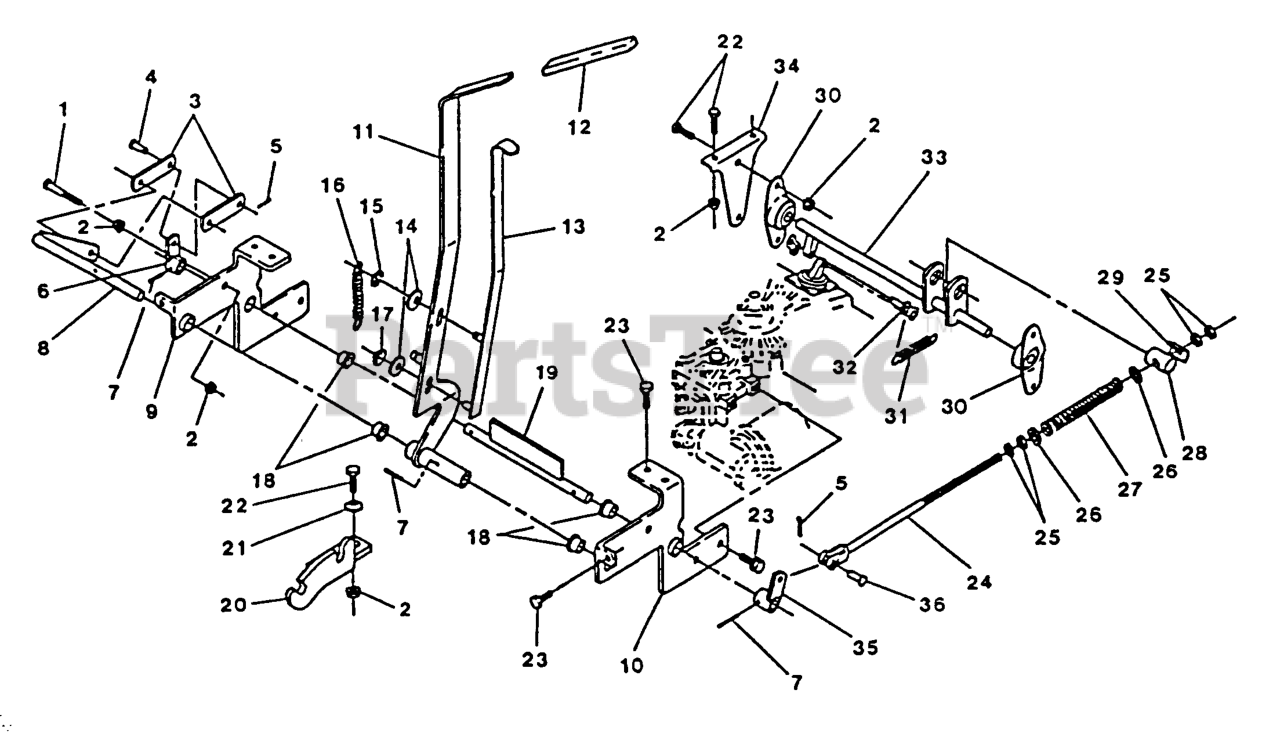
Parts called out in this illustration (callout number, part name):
3	LINK,BRAKE PLTD
4	PIN-CLEVIS
6	WLD,CONTROL ARM
8	PIVOT - BRKT/LEVER
12	GRIP-LEVER
16	SPRING,BRAKE HANDLE
17	NUT,PUSH
18	BEARING-CONTROL
19	WLD,BUTTERFLY
21	WASHER-SPRING
24	LINKAGE,BRAKE
27	SPRING,COMPRESSION
28	PIN,TRUNION
30	FLANGE MTG, SIDE
32	LINK-CONN#60
35	WLD,BRAKE CONTROL ARM
36	PIN-CLEVIS
